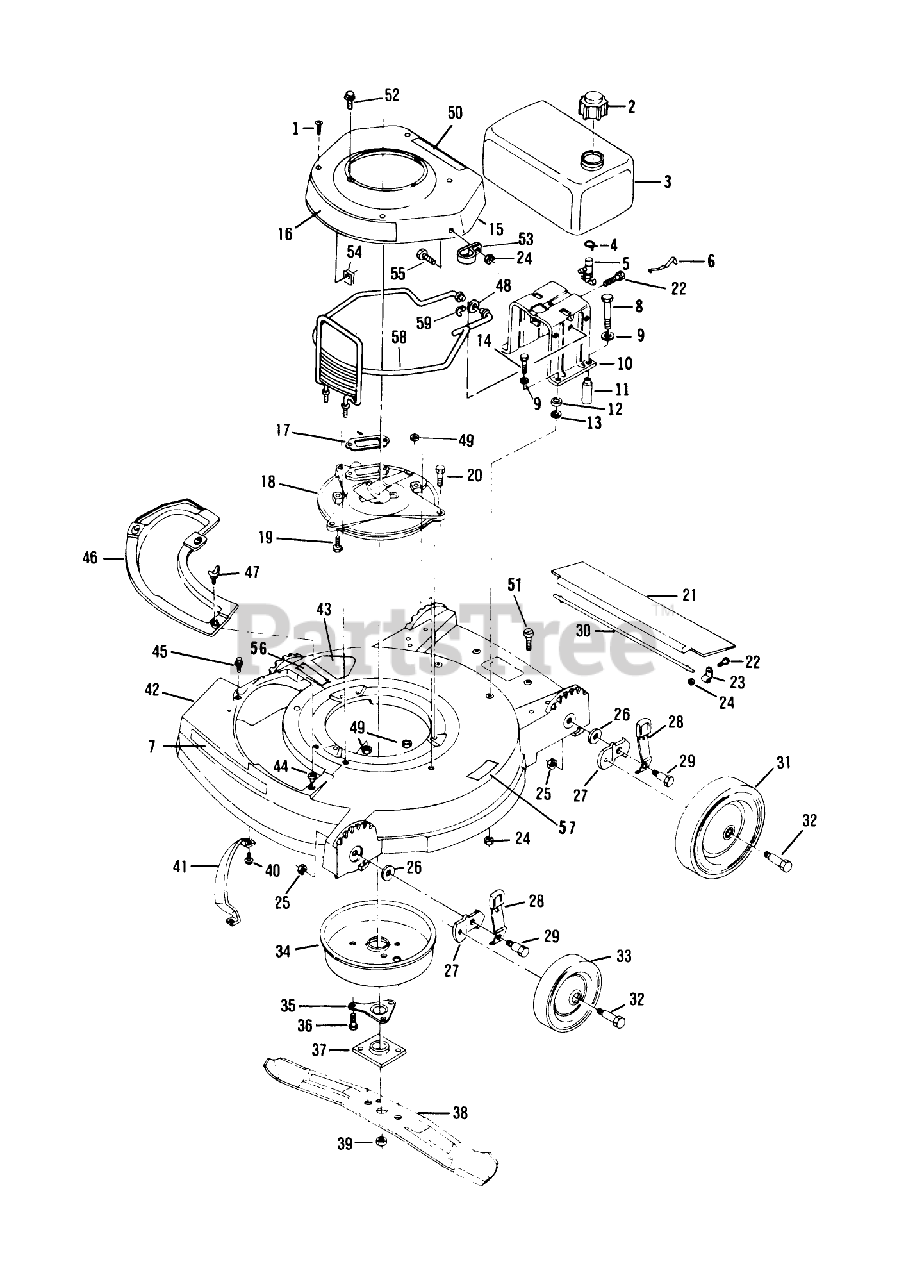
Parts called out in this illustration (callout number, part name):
1	SCREW - SELF TAPPING
2	FUEL CAP & INSERT
4	CLAMP - HOSE S
5	VALVE&SCREEN SM
6	SPRING
9	WASHER
13	WASHER
14	BOLT PIONEER
18	PLATE F
19	SCREW V
20	SCREW-HH
21	T/SHIELD GEAUGA
23	CLAMP ROD KMC
24	LOCKNUT E
25	LOCKNUT
26	WASHER
28	SPRING ARM ASM
29	BOLT
30	ROD 21" ADVANCE
31	WHL & TIRE AY
32	BOLT-SHOULDER
33	WHEEL & TIRE ASSY
34	MUFFLER COVER F
35	SUPPORT F
36	SCREW
37	PLATE AND COLLAR ASM
39	NUT-BLADE
41	BAR-TOE
47	WING SCREW LAWRE
48	WASHER SPRING LAR
49	NUT-LOCK F
52	SCREW SEMS SM
54	PUSHNUT F
59	HAIR PIN
